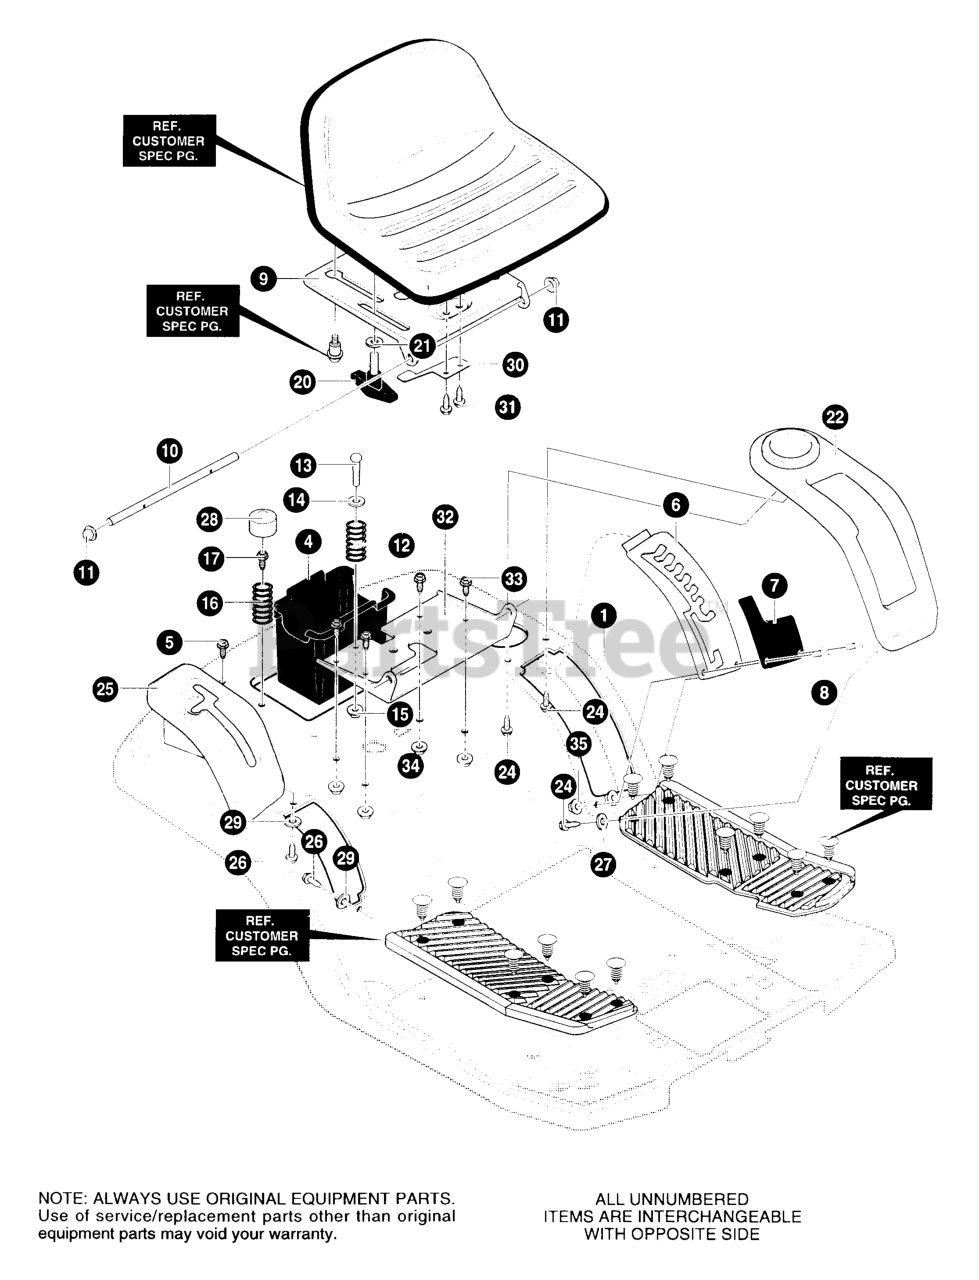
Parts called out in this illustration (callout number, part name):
1	SEAT DECK
4	CONTAINER, BATTERY
5	SCREW 1/4-20X.63 HHWATAPSER
6	PLATE, LIFT DETENT LG.
7	COVER, LIFT DETENT
8	SCREW,.230X.135 PPANTAP10-32B
9	SUPPORT, SEAT
10	HINGE SEAT PIVOT
11	NUT, PUSH CAP.375 (28X23)
12	SPRING, COMPRESS 4.57LGX1.17
13	BOLT, SHOULDER 1/4-20 NC-2A (9X55)
14	WASHER CUP ZINC
15	NUT, 1/4-20 WDFLLK
16	SPRING, COMPRESS 1.43LG 164X30
17	SCREW 5/16-18X.75 HHWATAPSGIB
20	BOLT, WING 5/16-18X.50 LG THRD
21	WASHER, FLAT .344X.62X.06
22	COVER,DETENT PLATE
24	SCREW, 1/4-15X.44/.53 HILOHHWA
25	COVER, SHIFT
26	SCREW, 1/4-15X.44/.53 HILOHHWA
27	FLATWASHER .286X.63X.065
28	CAP, HUB/SEAT SPRING
29	FLATWASHER.286X.63X.065
30	SPRING - LEAF
31	SCREW 1/4-20X.50 WAHHTAP
32	BRACKET, PIVOT SEAT
33	SCREW, 5/16-18 x .75 HHWATAP
34	SCREW, 10-24X.500TRSEGI
35	NUT, #10-32 CTRLK
